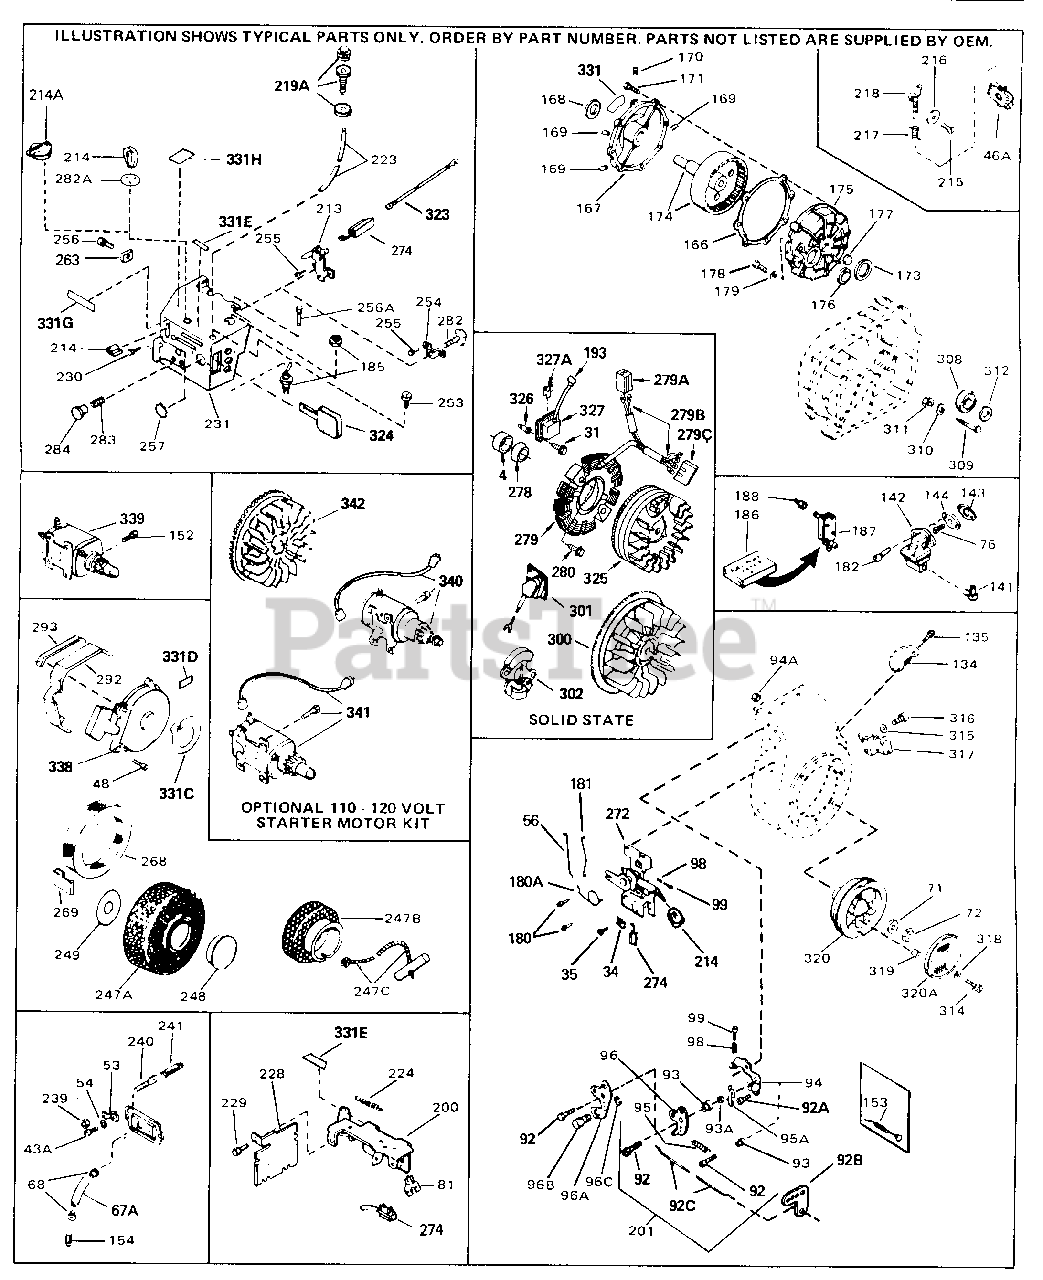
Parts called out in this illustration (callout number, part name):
4	Seal, Oil
31	Screw, 1/4-20 x 5/8"
34	Conduit Clip
35	Screw, 10-32 x 3/8"
43A	Screw, 10-24 x 1/2"
48	Screw, 1/4-28 x 7/16"
56	Link, Throttle
71	Washer, Belleville
72	Nut, Hex
98	Spring, Compression
99	Screw, 5-40 x 7/16"
134	Cover, Bubble
135	Screw, 8-32 x 3/8"
180	Screw, 10-32 x 1/2"
180A	Spring, Speed control
181	Link, Governor
193	Cover, Spark plug (Use as required)
214	Knob, Speed control
214A	Control Knob
223	Line, Primer
224	Spring, Extension
230	Screw, 8-32 x 5/16"
231	Cover, Carburetor
254	Bracket, Choke
255	Screw, 10-32 x 1/2"
256	Screw, 8-32 x 3/8"
256A	Screw, 10-32 x 1/2"
263	Nut, "U" Type (Use as required)
272	Control Bracket Incl. 98, 99, 180A & 274
274	Terminal Ass'y. As req. on late produ ction
292	Guard Starter
293	Seal, Snow guard
331	Decal, Instruction
331E	Decal, Primer
331G	Decal, Choke
331H	Decal, Warning
338	Rewind Starter Refer to Division 5, S ection C, page 29 for breakdown
340	Starter Motor Kit (110-120 Volt) This 110-120 volt starter motor kit may h ave been added to this engine. It can be added only if cylinder hasdrilled and tapped starter mounting bosses a nd a ring gear flywheel (see#342). Re fer to service number sta
342	Flywheel Ring gear flywheel requiredo n engines using 110-120 volt starter kits listed above
342	Flywheel (Used on Type letters H and above) (Std. Point ignition) (Ring ge ar flywheel required on engines using 110-120 volt starter kits listed abo ve)
342	Flywheel (Minimum ring gear flywheel required on engines using 110-120 vol t starter kits listed above) (Use wit hSolid State ignition)
